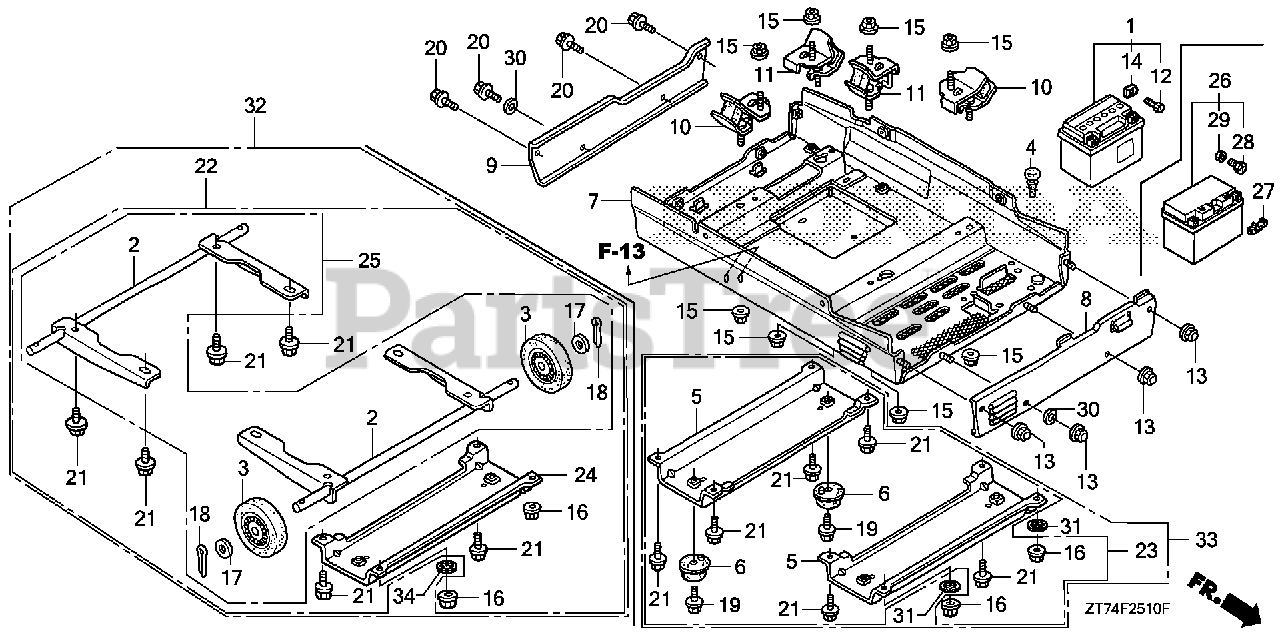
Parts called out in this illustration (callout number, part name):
3	WHEEL (100X32)
4	RUBBER, STAND STOPPER
6	RUBBER (LOWER) Use from Frame SN 1008046.
7	COVER (LOWER)
8	PLATE, FR. (LOWER)
9	PLATE, RR. (LOWER)
10	RUBBER, R. (LOWER)
11	RUBBER, L. (LOWER)
15	NUT, FLANGE (8MM)
16	NUT, FLANGE (8MM)
19	BOLT, FLANGE (6X10)
20	BOLT, FLANGE (6X10)
21	BOLT, FLANGE (8X14)
25	WHEEL KIT
26	BATTERY (YTZ10S) (YUASA) (MSDS)
27	RUBBER, BATTERY
28	BOLT, BATTERY TERMINAL
29	NUT, BATTERY TERMINAL
